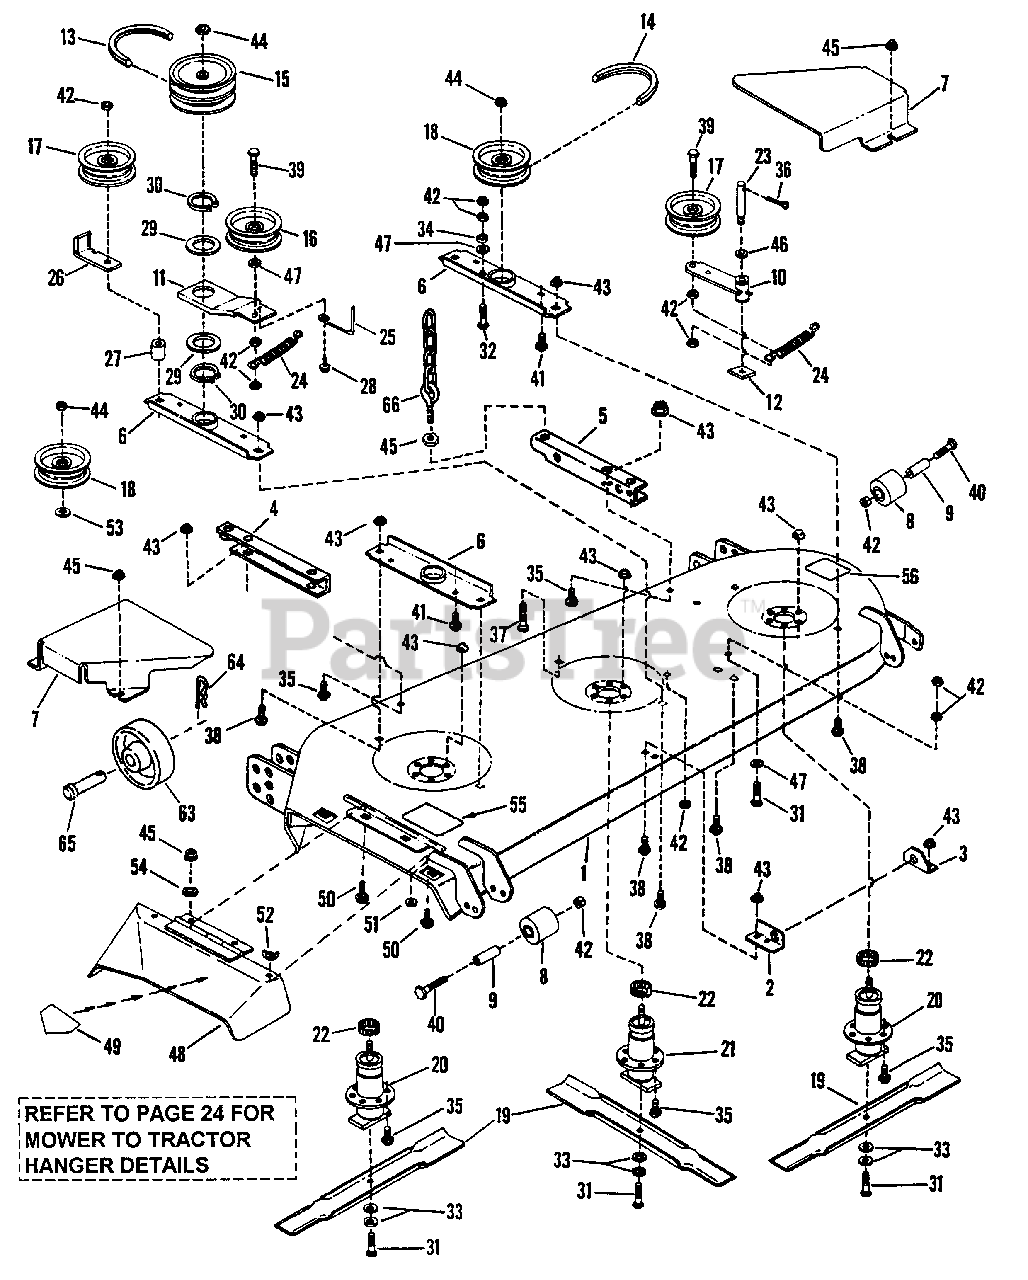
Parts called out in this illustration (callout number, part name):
1	DECK STRUCTURE - 48"
2	WELDMENT, Front Lift Arm
3	BRACKET, Front Hanger
4	SUPPORT, Rear Right (1985)
5	SUPPORT, Rear Left (1985)
6	BRACE, Spindle
7	GUARD, Pulley
8	ROLLER
9	SPACER
10	ASSEMBLY, Idler Arm
11	IDLER ARM, Center
12	WASHER - Square
13	V-BELT, Drive - A92
14	BELT, Deck - AA105
15	PULLEY, Double (4-3/4")
16	PULLEY, Flat Idler (4.8 O.D.)
17	PULLEY, V-Idler (4-1/2" O.D.)
18	PULLEY, 4-3/4" O.D.
19	BLADE, 16.5
20	ASSEMBLY, Spindle
21	ASSEMBLY, Spindle
22	TOLERANCE RING, 3/4"
23	IDLER STUD
24	SPRING
25	BELT GUIDE
26	BELT GUIDE
28	BOLT, 5/16-18 x 3/4" Short Square Neck, Grade 5
29	WASHER, Plastic
30	RING, 2" External Retaining
31	SCREW, 3/8-24 x 1-1/4" Hex Head Cap, Grade 5
32	SCREW, 3/8-24 x 1-1/2" Hex Head Cap, Grade 2
33	WASHER, Cone
34	SPACER
35	BOLT, 3/8-16 x 3/4" Hex Flange Lock
36	PIN, 1/8 x 1" Cotter
37	SCREW, 3/8-24 x 2-1/2" Hex Head Cap
38	BOLT, 3/8-16 x 3/4" Square Neck Carriage, Grade 2
39	SCREW, 3/8-24 x 2" Hex Head Cap, Grade 5
40	SCREW, 3/8-24 x 3-3/4" Hex Head Cap, Grade 5
41	BOLT, 5/16-18 x 5/8" Square Neck Carriage, Grade 5
42	NUT, 3/8-24 Hex Ctr. Lock
43	NUT, 3/8-16 Hex Fl. Lock
44	NUT, 3/4-16 Hex Jam
45	NUT, 5/16-18 Hex Fl. Lock
46	WASHER, 5/8 SAE
47	WASHER, 3/8 SAE
48	ASSEMBLY, Side Chute
49	DECAL, Danger
50	WASHER, 3/8 Split Lock
51	WASHER, 5/16 Split Lock
52	WING-NUT, 5/16-18
53	WASHER, 3/4 I.D.
54	RETAINER, 5/16 Bolt
55	DECAL, Caution
56	DECAL, Caution
63	WHEEL, 6.00" Gage
64	PIN, Hair Cotter
65	PIN, 1/2 x 3" Clevis
66	ASSEMBLY, Bolt/Chain
